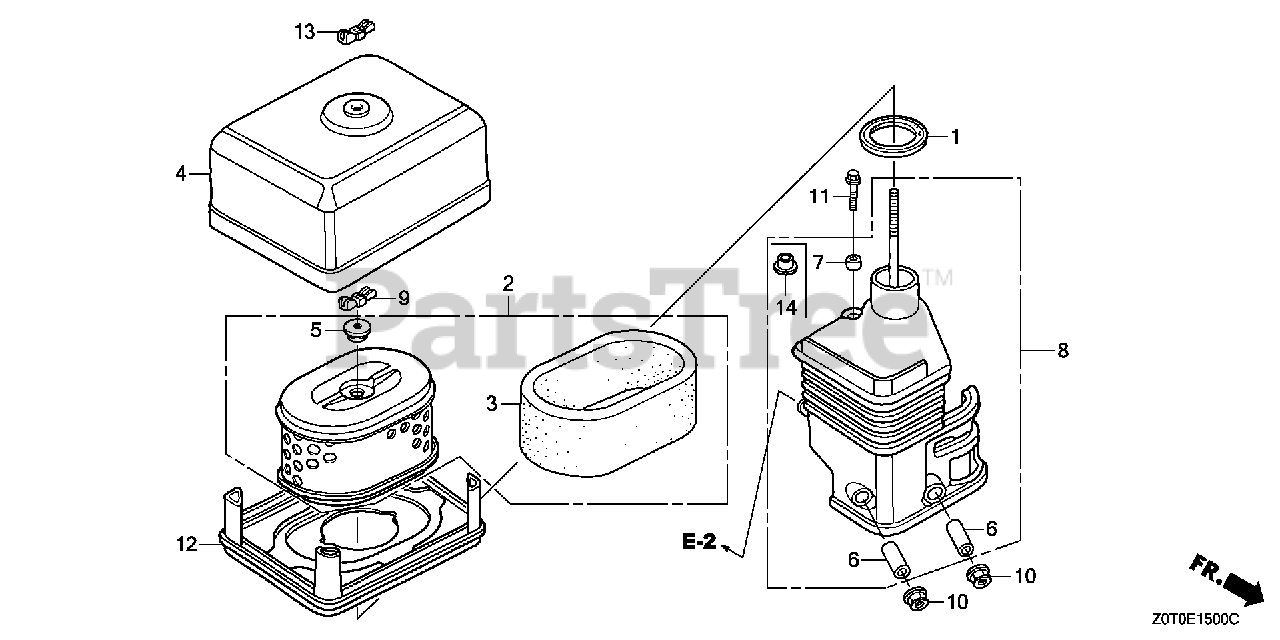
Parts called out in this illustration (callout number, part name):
1	GASKET, ELBOW
2	ELEMENT, AIR CLEANER (DUAL)
3	FILTER (OUTER)
4	COVER, AIR CLEANER (DUAL)
5	GROMMET, AIR CLEANER
6	COLLAR, AIR CLEANER
7	COLLAR B, AIR CLEANER
8	ELBOW, AIR CLEANER
9	NUT, TOOL BOX SETTING
10	NUT, FLANGE (6MM)
11	BOLT, FLANGE (6X20)
12	NOSE, MUFFLER
13	NUT, TOOL BOX SETTING
